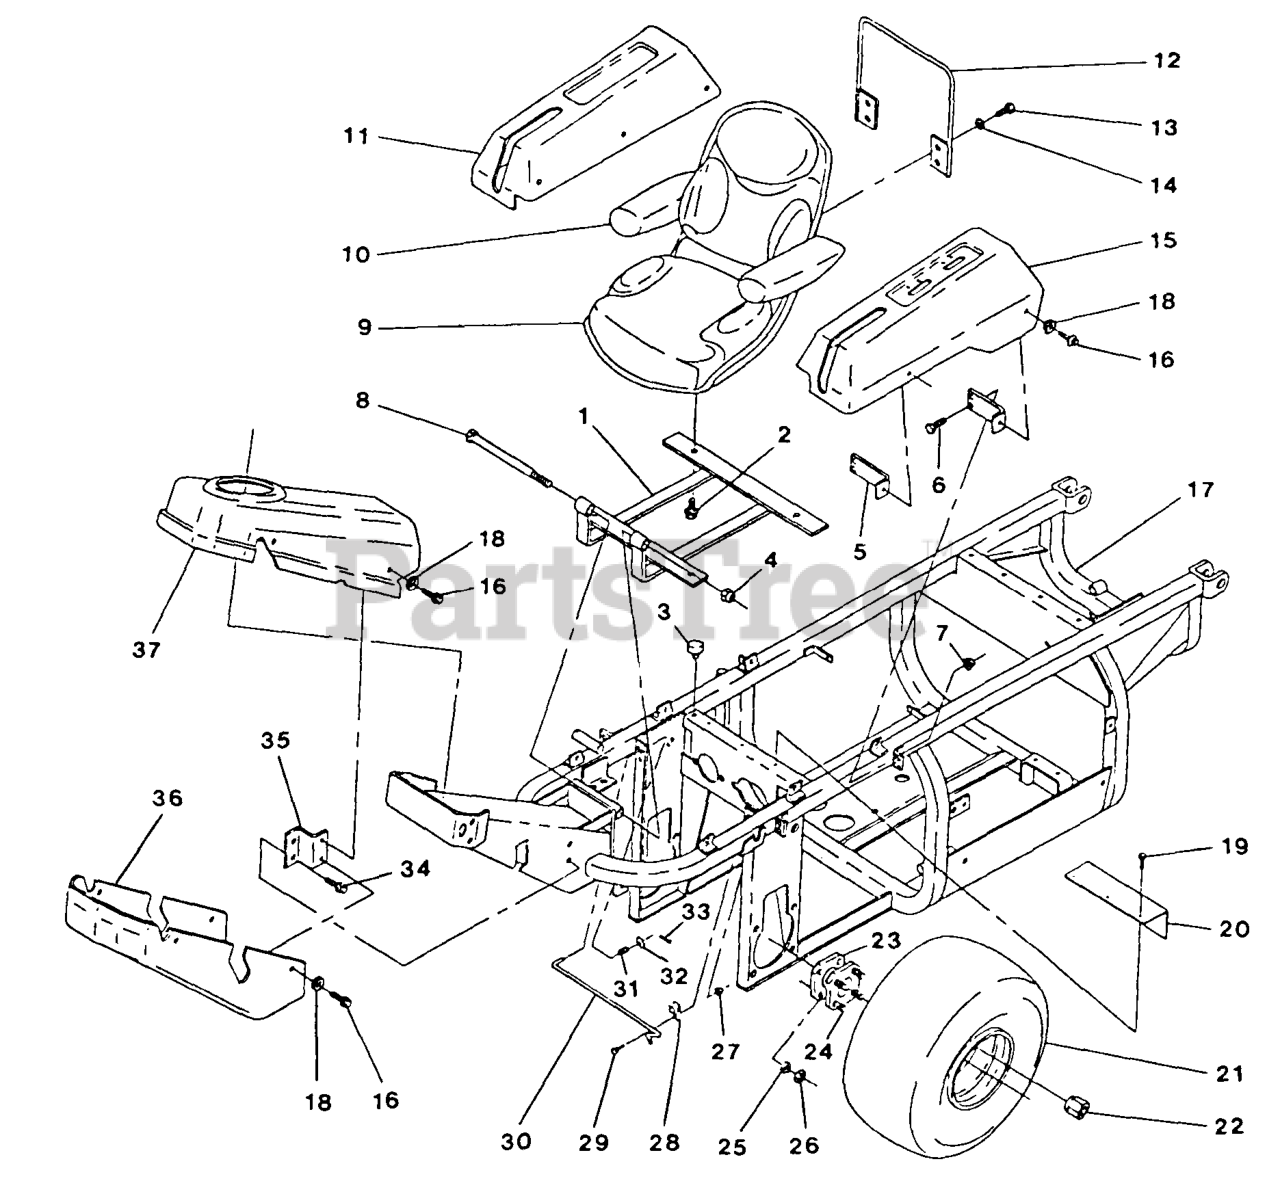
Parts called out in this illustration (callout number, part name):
11	FENDER,RH RANGER
15	FENDER,LH RANGER
24	BOLT - HUB
28	CLIP,SEAT HOLDUP ROD
30	ROD,SEAT HOLDUP
31	SPRNG,ST HOLDUP ROD
36	CONSOLE,STEERING BOTTOM
37	CONSOLE,STEERING TOP
